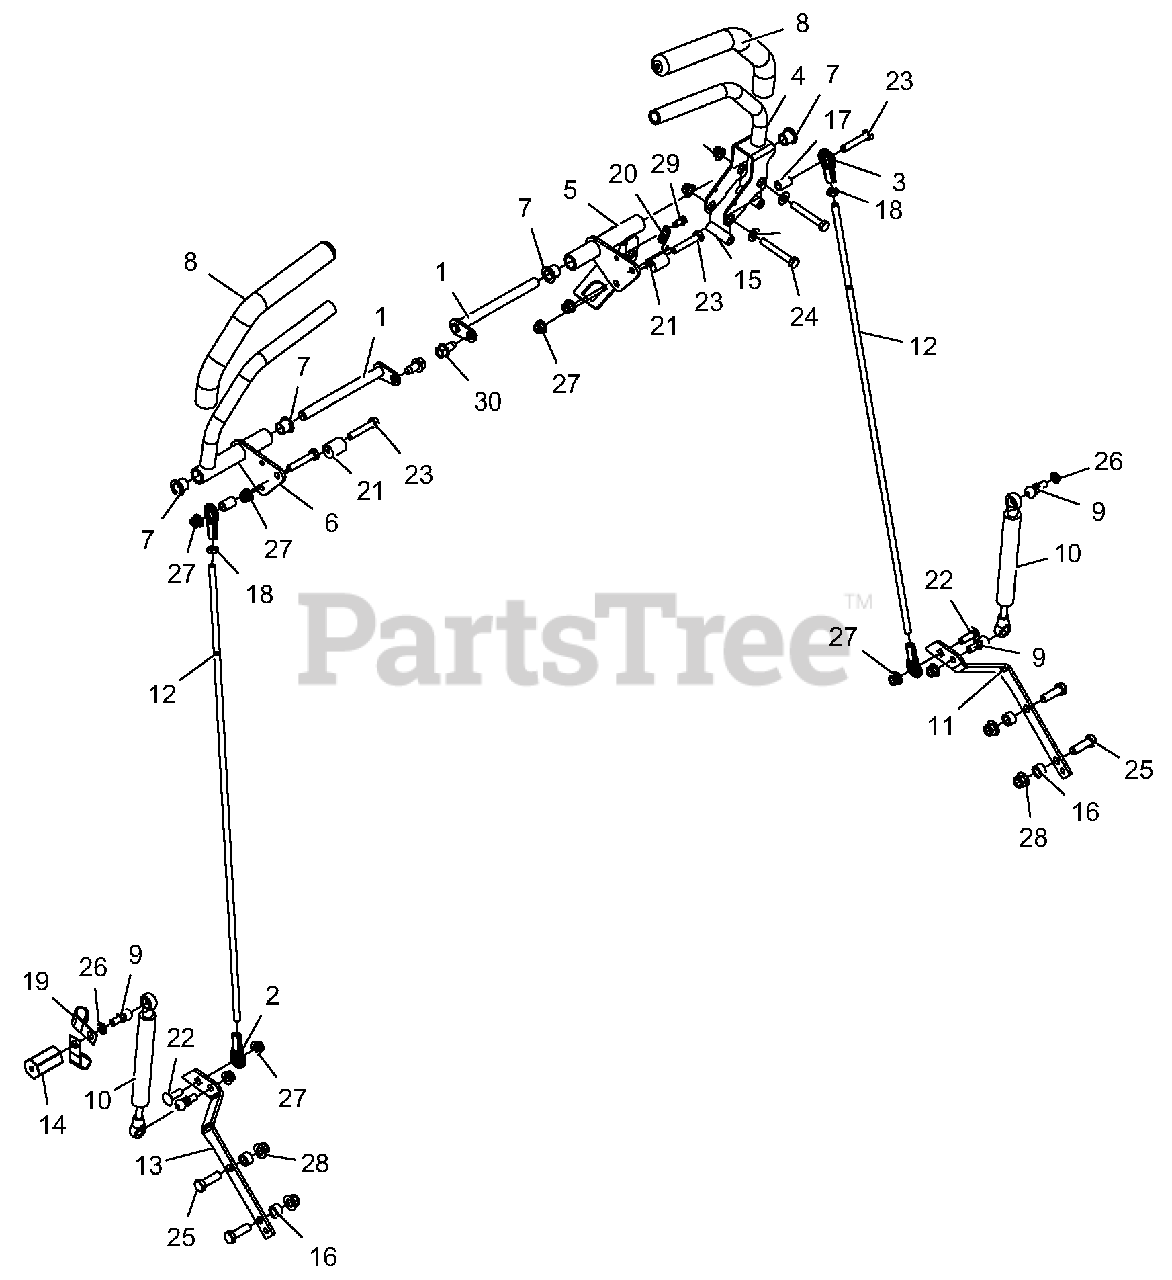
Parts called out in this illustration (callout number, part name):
1	WLDMT, PIN & LOCK
2	ALIGNABALL, 5/16 RH THREAD
3	ALIGNABALL, 5/16 LH THREAD
4	CONTROL, ARM , LH
5	WLDMT, CONTROL MOUNT (LH) - BLACK
6	WLDMT, CONTROL ARM (RH)
7	BRG, FLG .500 x .620 x .500 BRNZ
8	GRIP, HANDLEBAR REV
9	STUD-BALL
10	CONTROL DAMPER
11	BRKT, CONTROL LH
12	ROD, STEERING
13	BRKT, PROSTANCE CONTROL-RH - BLACK
14	SPCR, DAMPER PROSTANCE
15	BSHG, SLV .33 x .50 x 1.56
16	BSHG, SLV REV
17	BSHG-SLV .328 x .50 x .75
18	NUT, JAM -LH .31-24 YWZC
20	SPRG, EXTENSION
21	ECCENTRIC
22	BLT-RDHDSQSHNK .31-18 x 1.00 G5 Y
23	BLT-HEX .31-18 x 1.75 GR5 YWZC
24	BLT-HEX .31-18 x 2.25 GR5 YWZC
25	BLT-HEX .38-16 x 1.25 GR5 YWZC
26	WSHR-LK .31 x .078 REG YWZC
27	NUT-LK-NYL-FLG .31-18 YWZC
28	NUT-LK-NYL-FLG .38-16 YWZC
29	SCR-TAP .25-20 x .50 HWH TR YWZ
30	SCR-TAP .38-16 x .75 HWH TR YWZ
31	WSHR-FL-STL .344 x .688 x .065 YWZC
